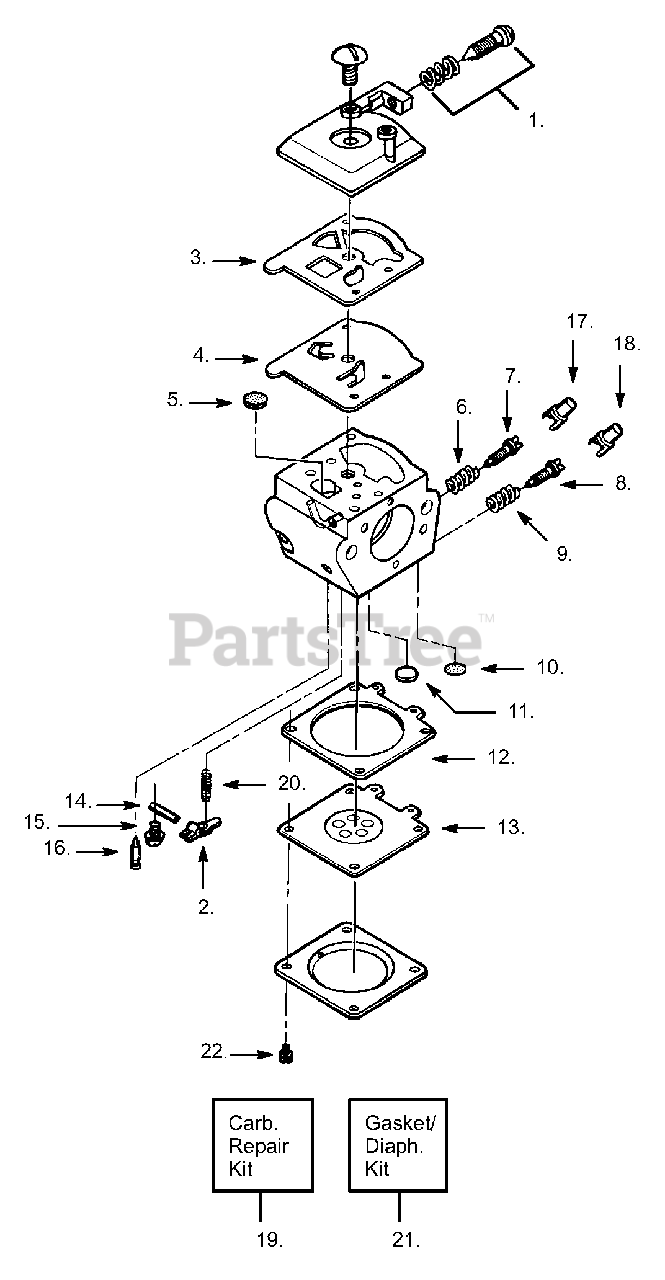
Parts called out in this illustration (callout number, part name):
1	Idle Adv. Screw Kit
2	Metering Lever
3	Fuel Pump Gasket
4	Fuel Pump Diaphragm
5	Fuel Inlet Screen
6	Needle Spring (Low Speed)
7	Low Speed Needle WT-202, 239 & 285
7	Low Speed Needle WT-289
8	High Speed Needle WT-202, 239 & 285
8	High Speed Needle WT-239
8	High Speed Needle WT-289
9	Needle Spring (High Speed)
10	Welch Plug (5/16)
11	Cup Plug
12	Metering Diaphragm Gasket
13	Metering Diaphragm
14	Metering Lever Pin
15	Metering Lever Pin Screw
16	Inlet Needle Valve
17	Limiter Cap - High WT-289 only
18	Limiter Cap - Low WT-289 only
19	Carburetor Repair Kit
20	Metering Lever Spring
21	Gasket/Diaphragm Kit
22	Metering Cover Screw Ass'y
